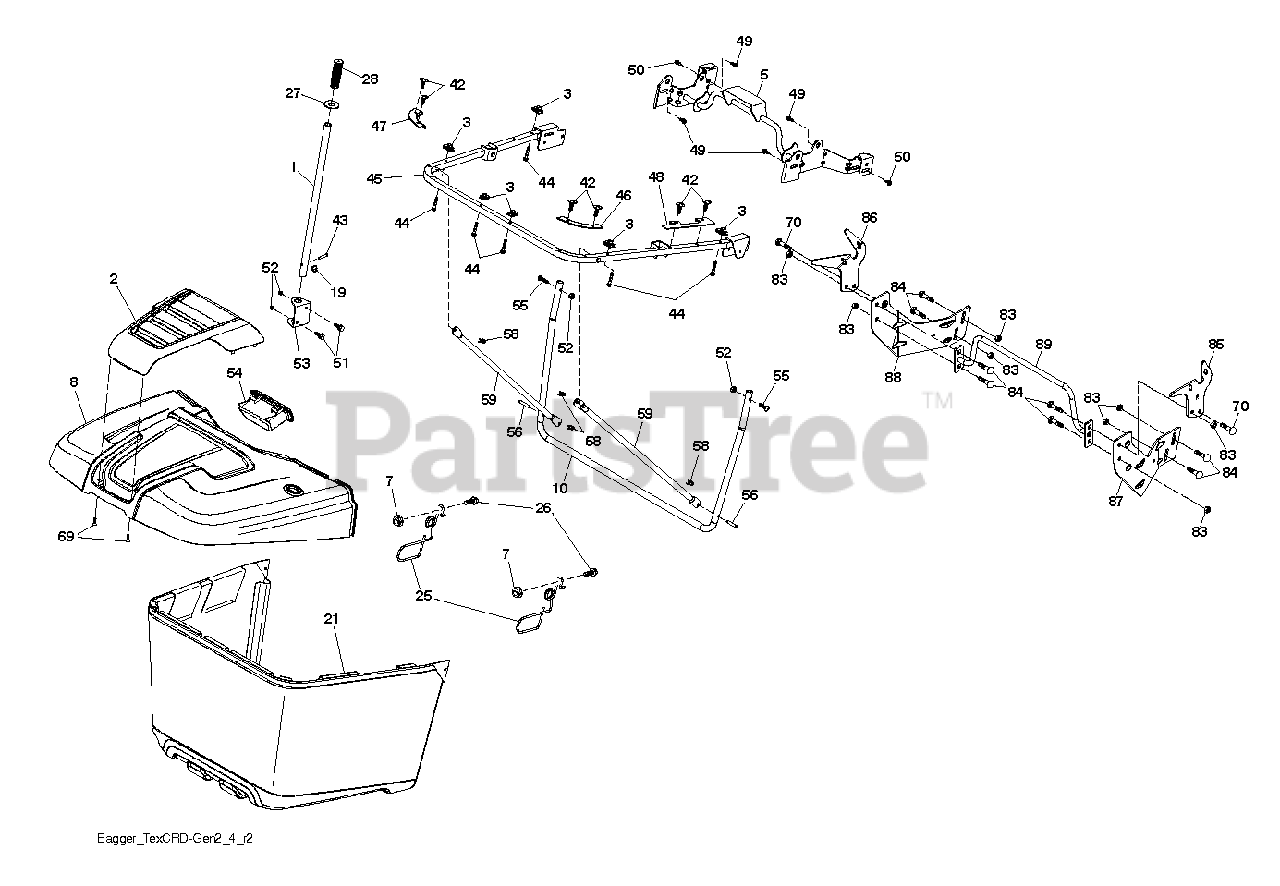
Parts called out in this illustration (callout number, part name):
1	TUBE.HANDLE.BAGGER.CRD/SRD.BLA
2	APPLIQUE.BAGGER
3	1/4-20 U NUT
5	FRAME TEX_CRD_GEN2 UPPER PIVOT
7	NUT T
8	BAGGER TOP
10	FRAME TEX_CRD_GEN2 BAGGER FRAM
19	PIN.COTTER.5/16.BOW TI
21	BAG FRAME BAGGER ASSEMBLY. HUS
25	LATCH LATCH. BAG. CRD GEN 2
26	SCREW HEX CRT
27	GROMMET RUBBER GROMMET, DUMP T
28	GRIP.HANDLE.BLACK
42	CLIP CHRISTMAS TREE CLIP
43	RIVET,DRILLED
45	FRAME TEX_CRD_GEN2 UPPER U FRA
46	CONNECTOR RIGHT BAGGER CORNER
47	CONNECTOR LEFT BAGGER CORNER C
48	BAFFLE BAGGER SIDE CLOSE-OUT
49	BOLT, SHOULDER 5/16-18
50	BOLT, 5/16-18 X 1 3/4
51	BOLT.CARR.SQNK.5/16-18UNC.X3/4
52	NUT.71038.31-18.HEX.NYLOCK
53	BRACKET DUMP HANDLE BRACKET, T
54	HANDLE BAGGER TOP FRONT HANDLE
55	BOLT
56	PIN.CLEVIS.183
58	RETAINER CLIP PM
59	TUBE BAGGER SPREADER TUBE, TEX
69	SCREW,#8.FLAT.HEAD.DRILL.TIP
70	SCREW, 3/8-16X3/4
83	NUT
84	BOLT D
85	BRACKET.RH.PIVOT.MAN.DUMP.BLAC
86	BRACKET.LH.PIVOT.MAN.DUMP.BLAC
87	BRACKET.RH.MID.SUP.BAG.TEX.CRD
88	BRACKET.LH.MID.SUP.BAG.TEX.CRD
89	TUBE.WELD.OFSET.STRUT.BAG.X431
